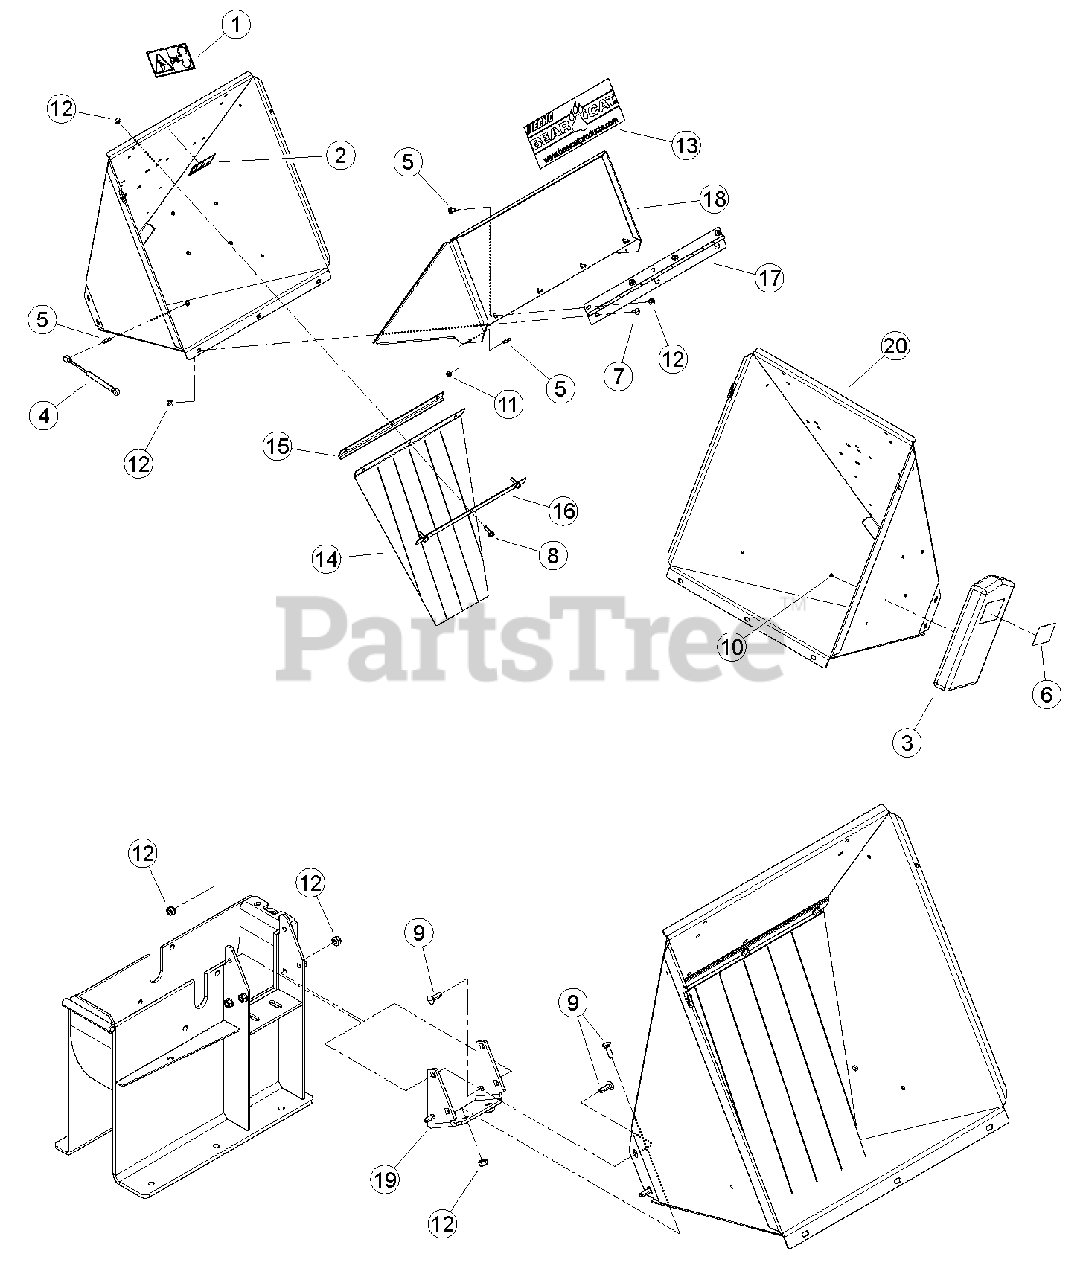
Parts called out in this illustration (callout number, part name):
1	DECAL, BLADE DANGER ISO
2	DECAL, MAINTENANCE ISO
3	CONTAINER, INSTR. MANUAL
4	SPRING, GAS 60 PSI
5	STUD, BALL .39
6	DECAL, MUTILINGUAL MANUAL
7	BOLT, 3/8 X 1" GR5 CRG NC ZP
8	BOLT, 3/8 X 1-1/4 FLANGE NC
9	BOLT, 3/8 X 1-1/4" GR5 CRG NC ZP
10	RIVET, 1/4 X 1/2 DOME HD BLIND SS
11	NUT, 5/16-18 NYLOCK-FLANGE
12	NUT, 3/8-16 NYLOCK FLANGE
13	DECAL, BEARCAT WEB
14	FLAP, CHIPPER CHUTE
15	ANGLE, FLAP ANCHOR
16	STRIP, FLAP RETAINER
17	HINGE, EXTENSION TRAY
18	WELDMENT, EURO 5 IN CHUTE TRAY
19	BRACKET, CHUTE MOUNT
20	ASSEMBLY, 5 IN CHIPPER CHUTE XE
